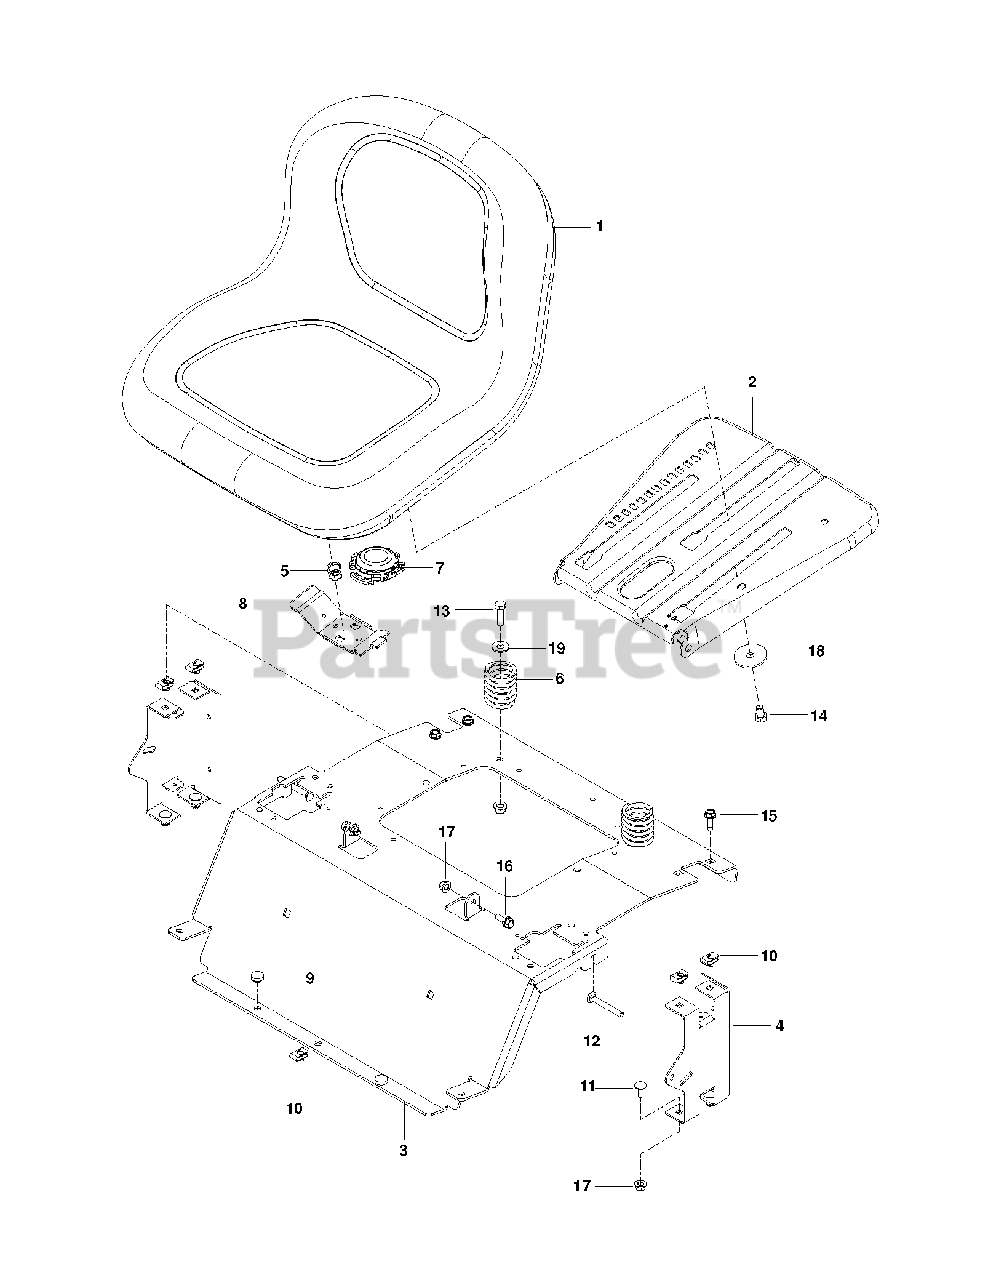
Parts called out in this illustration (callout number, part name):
1	SEAT.TG150.BLK.NLOGO.
2	PAN.ASM.SEAT.3PT
3	SUPPORT SEAT BLUE
5	SPRING, SEAT
6	SPRING.LATCH.SEAT.TEX
7	SWITCH, SEAT N/C
8	HANDLE.SLIDE.SEAT.TEX.BLACK
9	GROMMET, BUMPER
10	U-CLIP 5/16-18 NUT RETAINER
11	BOLT 5/16C X 3/4" CARRIAGE
12	RHSNB 5/16-18 X 2-1/2 GR5 ZD
13	HCS 3/8C X 1 1/4 GR5
14	HCS 3/8-16 X 5/8 GR 5 ZD
15	BOLT 5/16-18 X 3/4
16	BOLT, SHOULDER
17	5/16-18 NYLOC FLANGE NUT
18	WASHER, 3/8 SPEC
19	WASHER 3/8 FLAT
